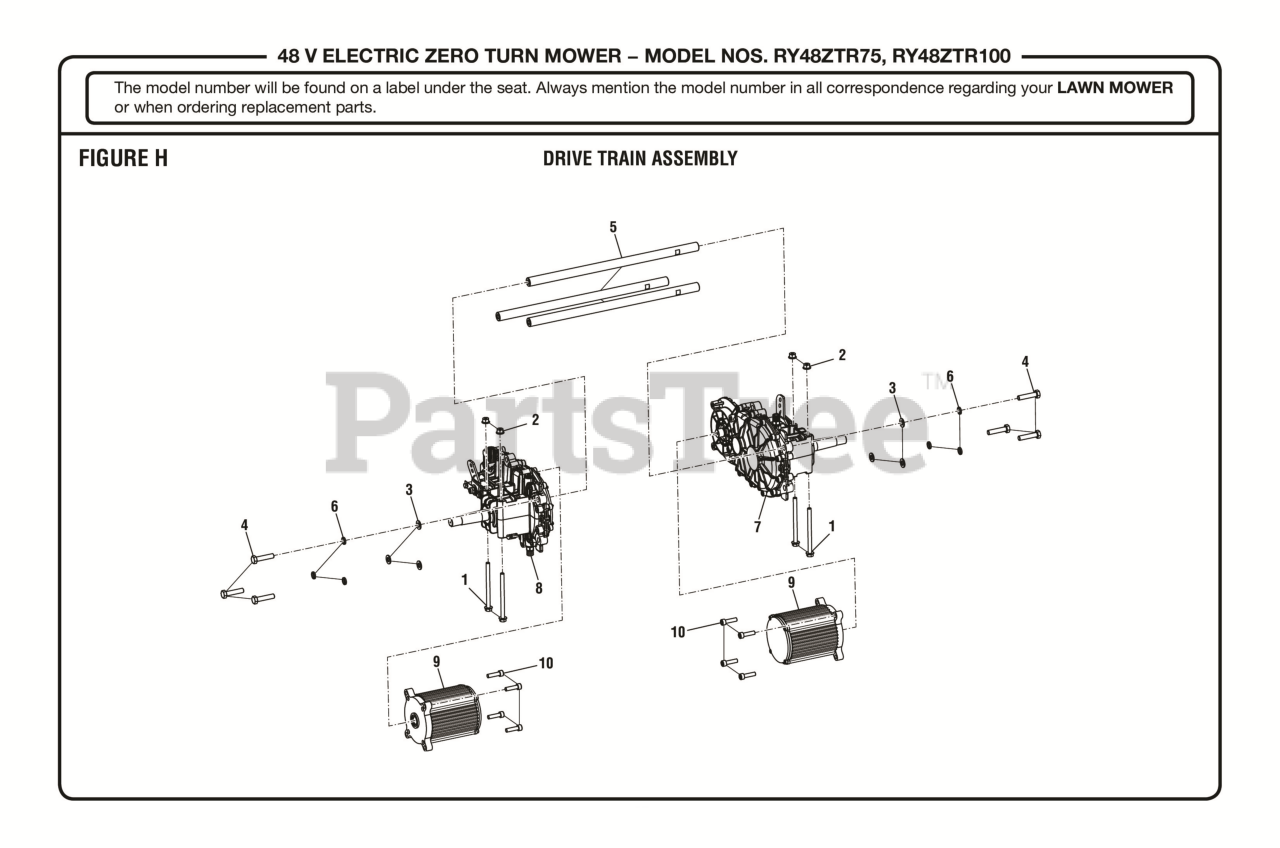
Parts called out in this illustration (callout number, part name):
1	Flange Bolt (M8 x 110 mm, Hex Hd.)
2	Flange Nut (M8) (For Drive Motor Controller V)
3	Washer (OD20 x ID10.5 x 2t)
4	Bolt (M10 x 45 mm, Hex Hd.)
6	Lock Washer (M10)
7	Gearbox, Left
8	Gearbox, Right
9	Drive Motor, ZTR
10	Screw (M8 x 30 mm, Soc Hd.)
